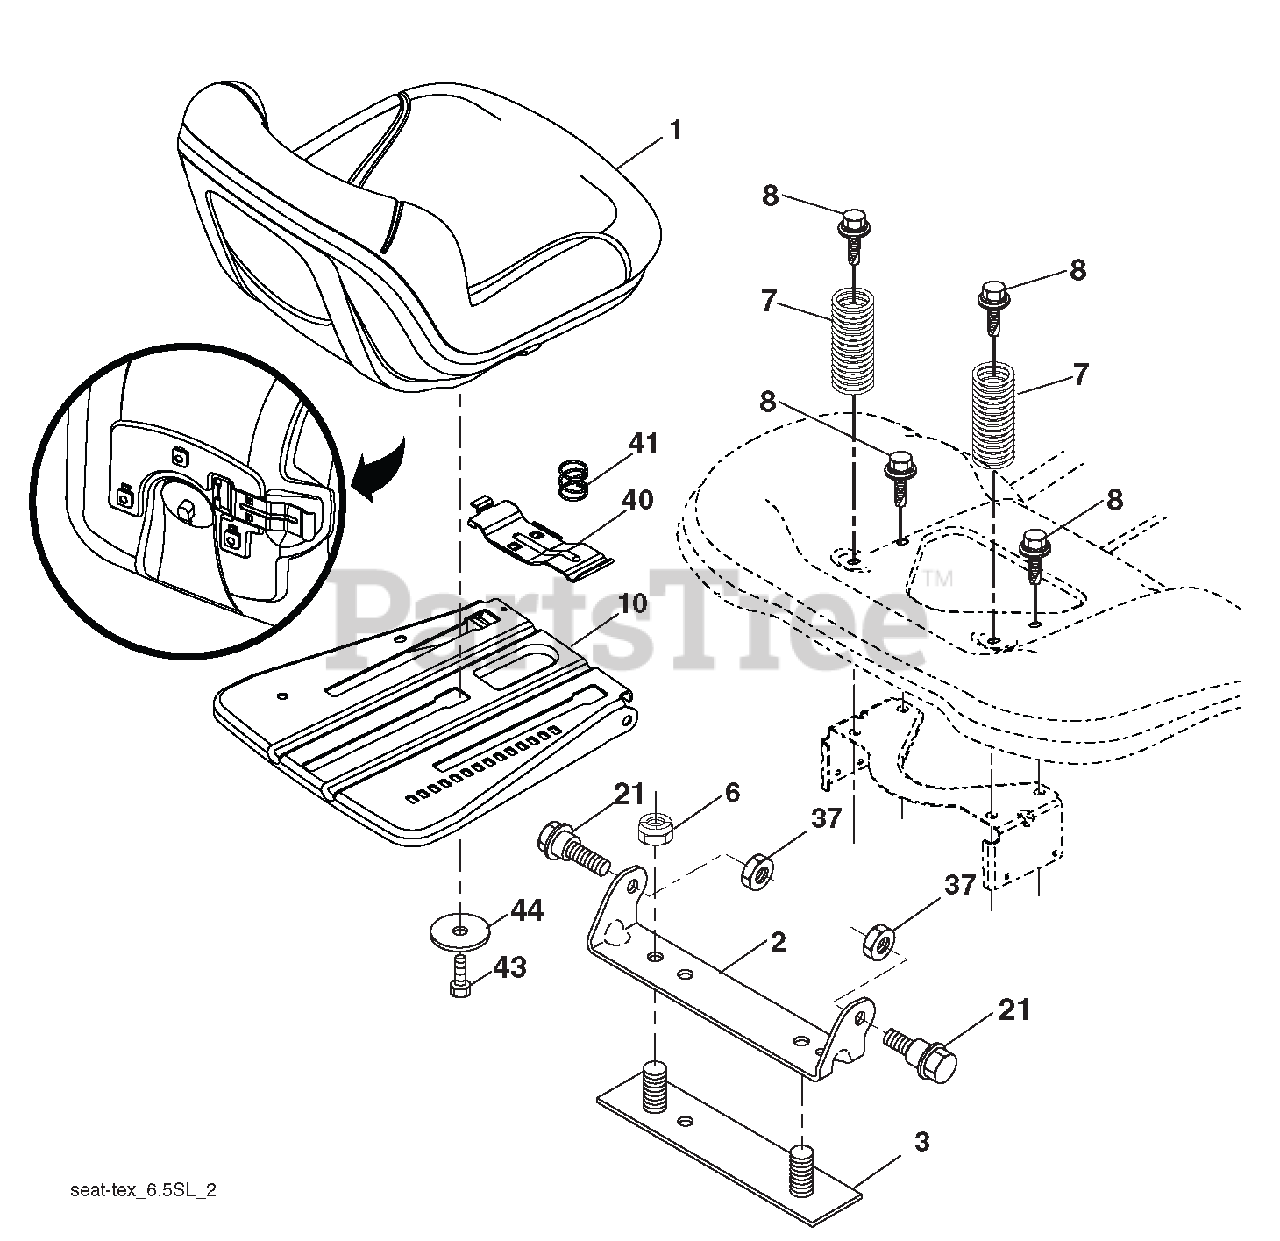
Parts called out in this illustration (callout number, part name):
1	SEAT.TA150.KB/SLD.BLK.ARIENS
2	BRACKET.PIVOT.FENDER.2002
3	STRAP ASM.FENDER.94
6	Locknut, Washer Insert 3/8-16
7	SPRING.SEAT.CPRSN.2.250.BLK.ZI
8	BOLT.5/16-18UNCX3/4 W/SEMS.BLK
10	PAN ASM.SEAT.3PT.
21	BOLT.SHLD.5/16-18 UNC-2A.BLK D
37	Locknut, Washer Insert 5/16-18
40	HANDLE.SLIDE.SEAT.TEX.MILSCO
41	SPRING.LATCH.SEAT.TEX
43	BOLT.FIN.HEX.3/8-16UNC X 3/4
44	WASHER.13/32 X 2 3/8 X 12GA.
